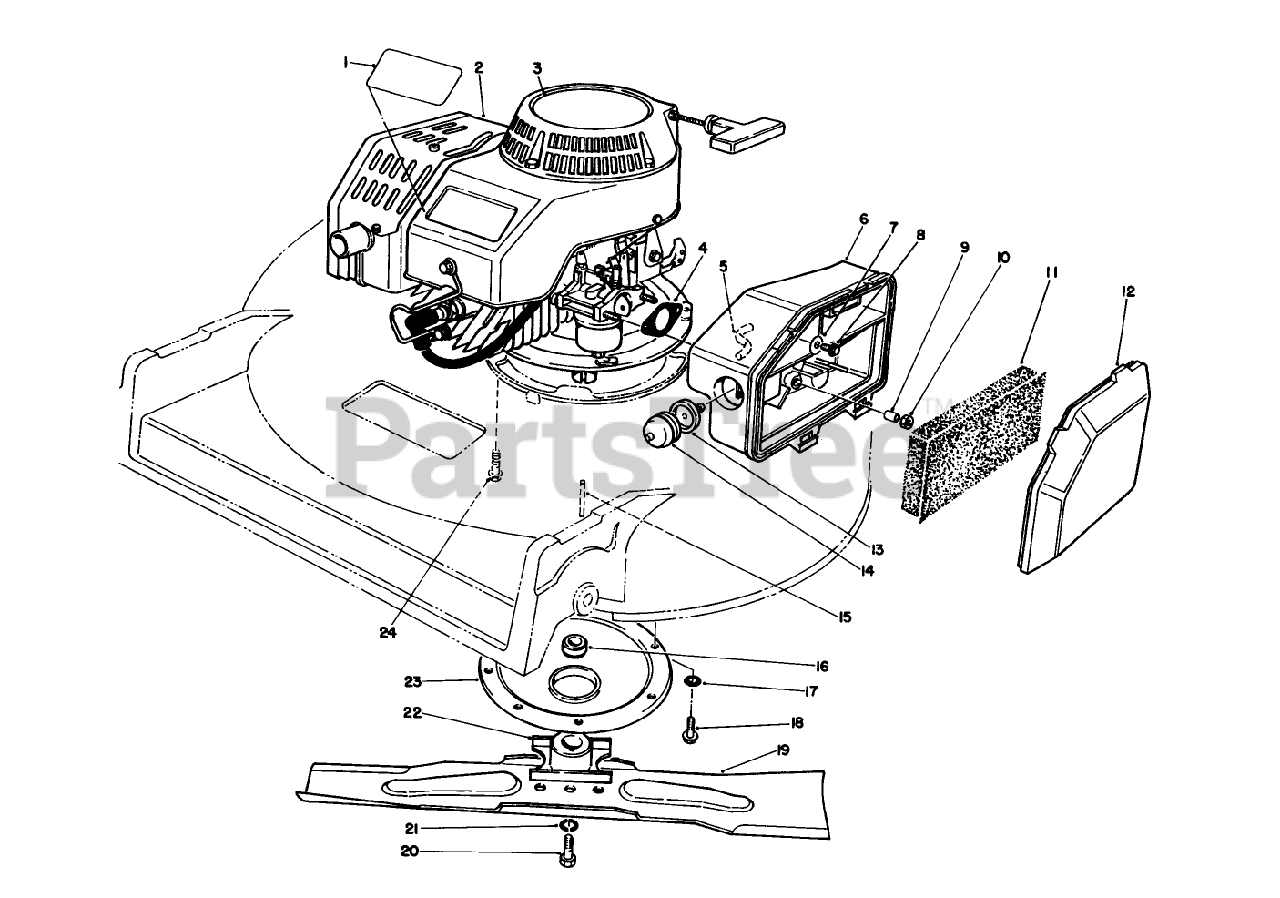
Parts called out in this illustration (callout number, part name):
1	DECAL - PROLINE
2	Complete Engine
3	DECAL-2 CYC RECOIL COMM
4	GASKET-AIR CLEANER
5	HOSE-PRIMER
6	BODY-AIR CLEANER
7	WASHER-FLAT
8	SCREW-HH
9	SPACER
11	ELEMENT-AIR CLEANER
12	COVER-AIR CLEANER
13	BODY-PRIMER
14	BULB-PRIMER
15	KEY-SQUARE
16	SPACER-BLADE RETAINER
17	WASHER-LOCK, INTERNAL
18	SCREW-HWHTF
19	Key
20	SCREW-BLADE
21	WASHER-LOCK
22	RETAINER-BLADE
23	PROTECTOR-CRANKSHAFT
24	SCREW-HHF
